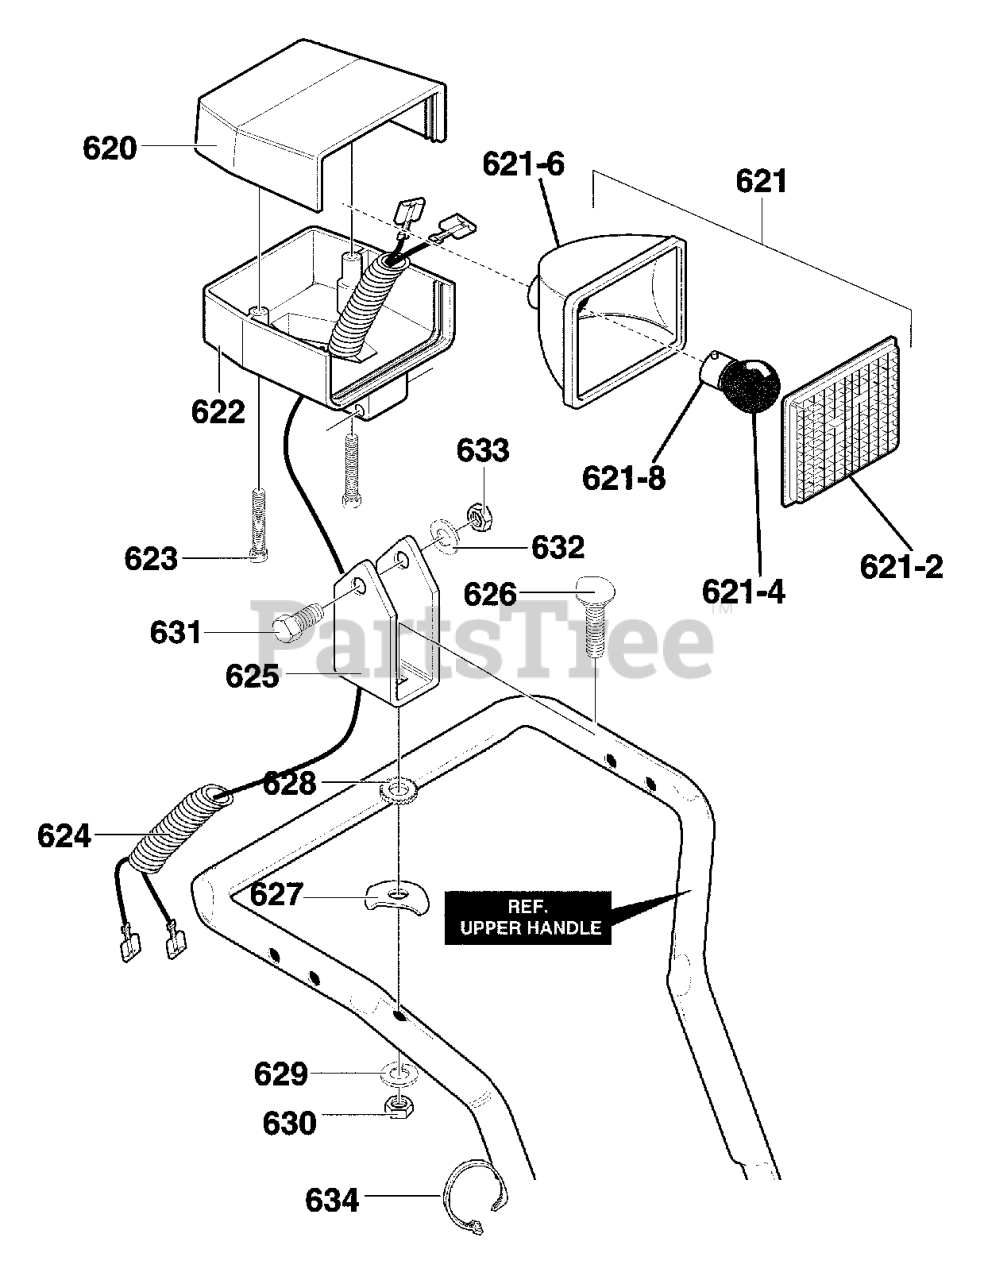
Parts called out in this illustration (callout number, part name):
620	HOUSING, HEADLIGHT UPPER
621	HEADLIGHT, ASSY
621-4	BULB 1156
621-6	BACK, METALIZED
622	HOUSING, HEADLIGHT LOWER
623	SCREW, #8X1.75
624	WIRING HARNESS
625	BRACKET, HEADLIGHT
626	BOLT, 5/16-18X1.75 CARR.
627	WASHER, SADDLE
628	WASHER, EXLK .32X.60X.040
629	WASHER, SPTLK .31X.58X.08
630	NUT, 5/16-18 REGHEX
631	SCREW, 5/16-18 x 2.00
632	WASHER, SPTLK
633	NUT, 5/16-18 REGHEX
634	TIE, CABLE
